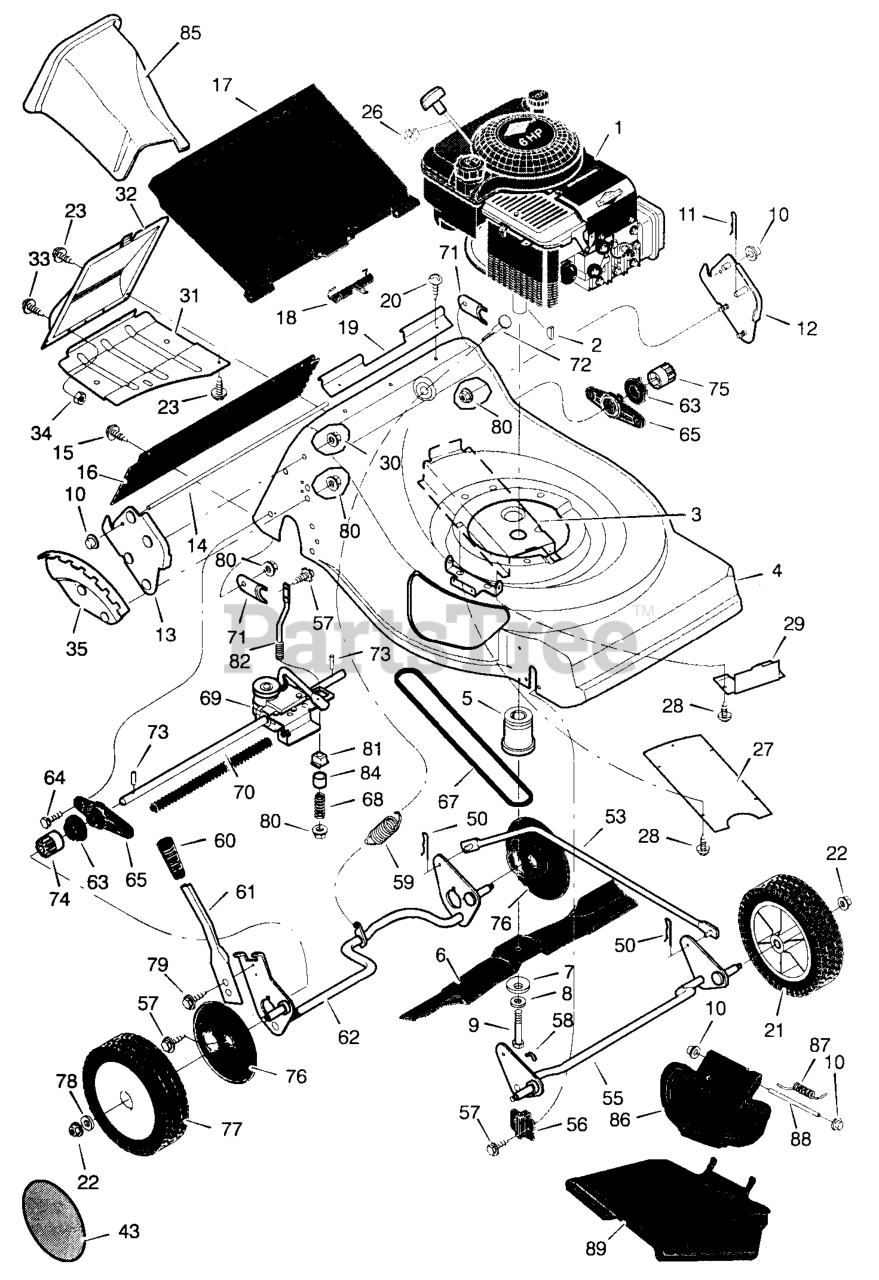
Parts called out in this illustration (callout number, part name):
1	Engine *
2	Key, Woodruff
3	Bolt, Engine
4	Housing
5	Adapter, Blade
7	Washer, Belleville
10	Push On Cap
11	Pin, Hair
12	Handle Bracket, Left
13	Handle Bracket, Right
14	Rod, Door Pivot
16	Deflector, Rear
17	Door, Rear
18	Spring, Torsion
19	Spacer, Door
21	Wheel, Front
22	Nut
26	Stop, Rope
27	Cover, Belt
29	Cover, Front Belt
30	Nut, Hex Flange
31	Cover, Lower
32	Cover, Rear
35	Bracket, Index
43	Hub Cap
53	Link, Lifter
55	Crossbar, Front
56	Clip, Retainer
58	Bushing
59	Spring, Extension
60	Grip, Height Adjuster
61	Lever, Height Adjuster
62	Crossbar, Rear
63	Bearing, Lifter
64	Bolt, Hex
65	Support, Axle
67	Belt, Drive
69	Transmission
70	Shield, Axle
71	Retainer, Bearing
72	Support, Lifter Spring
73	Pin, Drive
74	Pinion, Right
75	Pinion, Left
76	Cover, Dust
77	Wheel, Drive
78	Washer, Thrust
80	Locknut
81	Bushing
82	Support, Spring
85	Plug, Mulcher
86	Cover, Mulch
87	Spring, Torsion
89	Deflector, Chute
